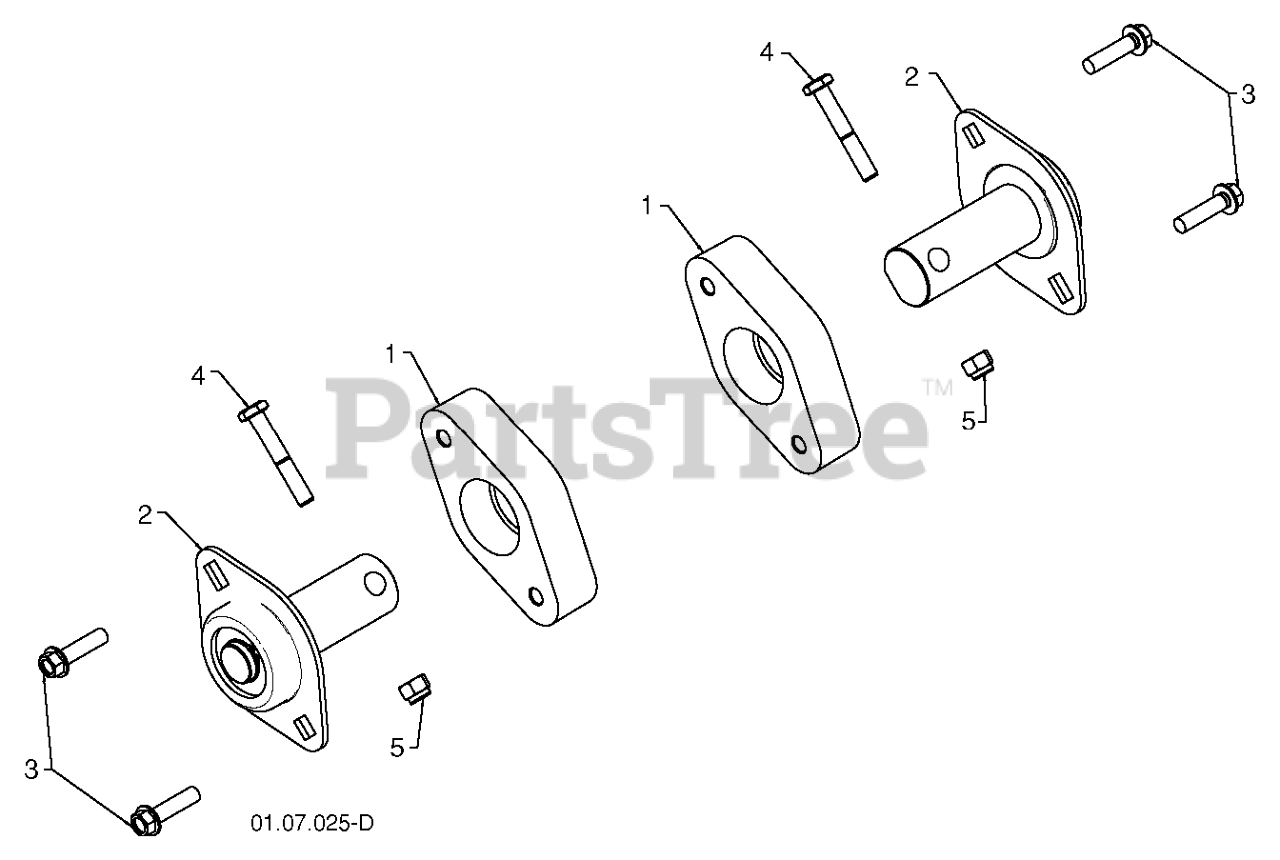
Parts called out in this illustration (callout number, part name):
1	BEARING RETAINER, PLASTIC
2	RP.BEARING.BALL.AUGER.FLAT.SNO
3	SCREW, HEX HD 5/16X1
4	SCREW.HEX.HD1/4-20X
5	LOCKNUT.NYLOC.1/4-20
